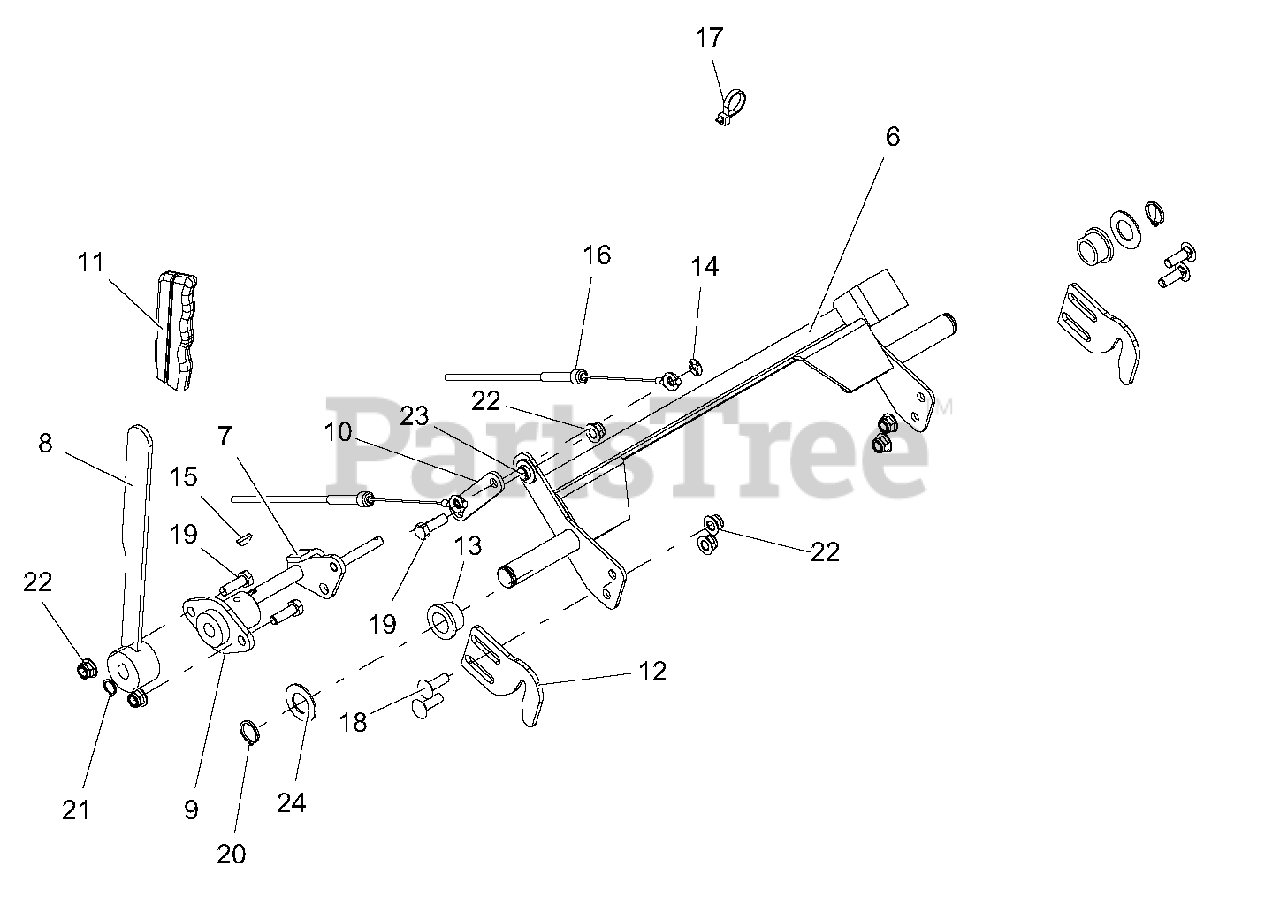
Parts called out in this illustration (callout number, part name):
6	WLDMT, PT100 NEUTRAL LOCK
7	WLDMT, PARK BRAKE ARM
8	WLDMT, PARKING BRAKE ARM
9	BSHG, FLANGE .500 ID
10	PLATE, NEUTRAL INTERLOCK
11	GRIP, PARKING BRAKE (YELLOW)
12	NEUTRAL, LOCK LATCH-BLACK
13	BSHG, -- FLG .750X1.000X.625X1.250
14	NUT, PUSH .312
15	KEY, WDRF .13x.63 HRD#5 GM124545 P
16	CABLE, BRAKE ACTUATING
17	CABLE TIE
18	@BLT-RDHDSQSHNK .31-18X1.00 G5 Y
19	@BLT-HEX .31-18X1.00 GR5 YWZC
20	RG-RTNG-EXT .750x.078
21	RG-RTNG-EXT .500x.050
22	NUT-LK-NYL-FLG .31-18 YWZC
23	BSHG, FLG .325X.499X.26X.88
24	WSHR-FL-STL .755X1.375X.062 YWZC
